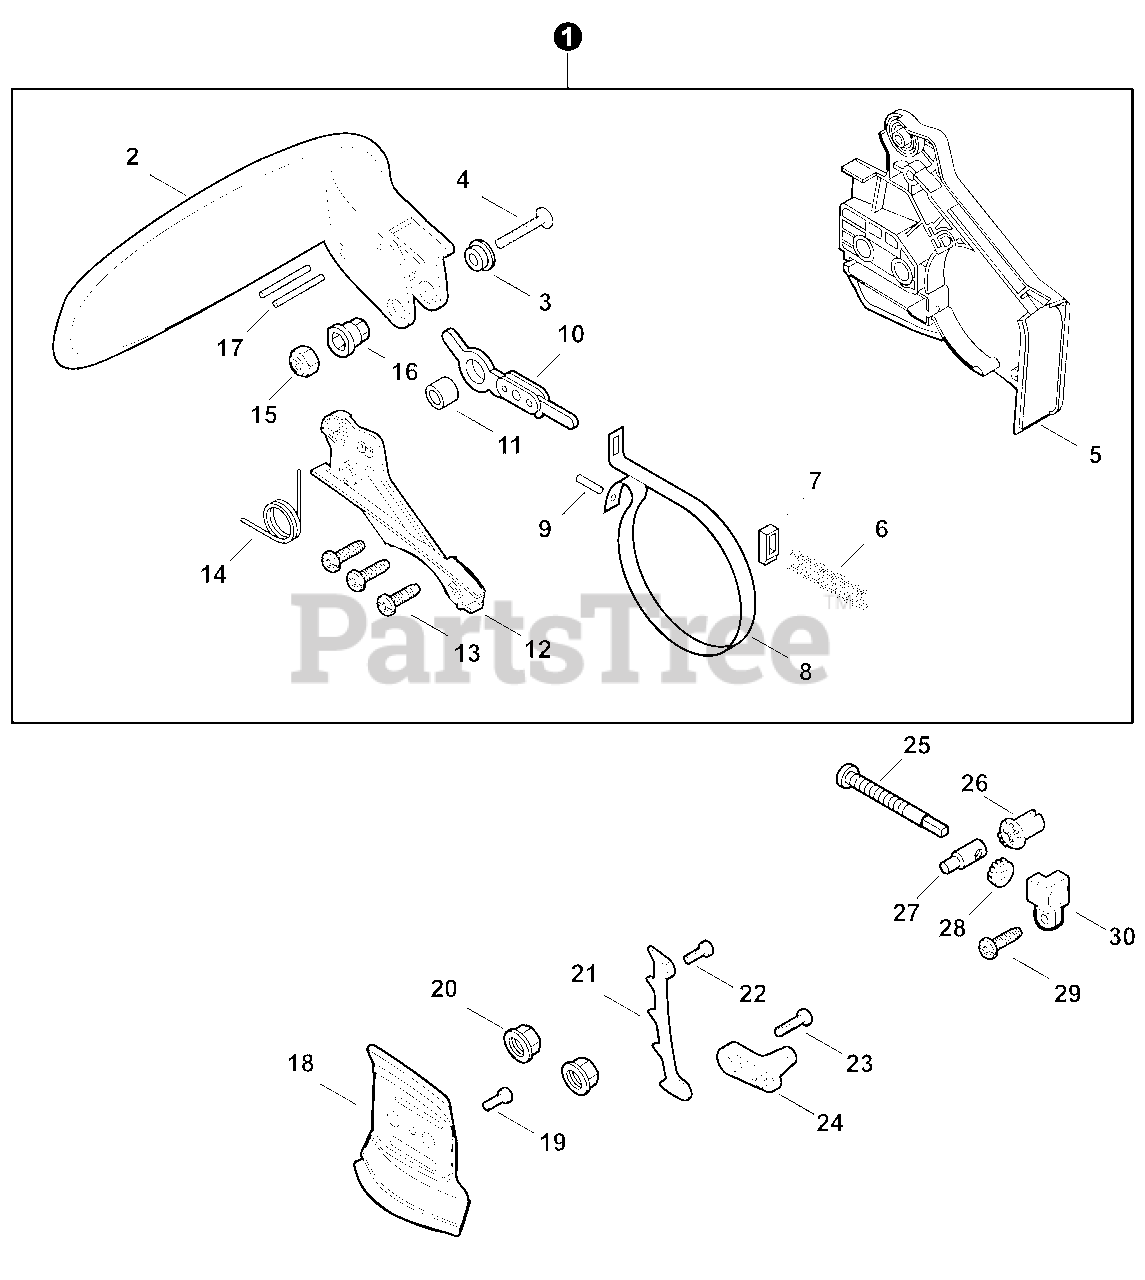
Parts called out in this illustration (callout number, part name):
1	BRAKE ASSY, CHAIN
2	LEVER, BRAKE - ORANGE
3	COLLAR 5.3×10×13×L5
4	SCREW 5×32
5	GUARD, SPROCKET
6	SPRING, COMPRESSION
8	BAND, BRAKE
9	PIN, SPRING 3×9.8
10	CONNECTOR, BRAKE
11	SPACER 8×12×9
12	COVER, BRAKE
13	SCREW 4×12
14	SPRING, TORSION
15	NUT, LOCK M5
16	COLLAR 5
17	PIN 3×26
18	PLATE, GUIDE - INNER
19	SCREW 4×10
20	NUT, FLANGE 6
21	SPIKE, BUMPER
22	SCREW 5×20
23	SCREW 5×20
24	CHAIN CATCHER
26	GEAR, BEVEL
27	TENSIONER, CHAIN
28	GEAR, BEVEL
29	SCREW 4×12
30	COLLAR 8
